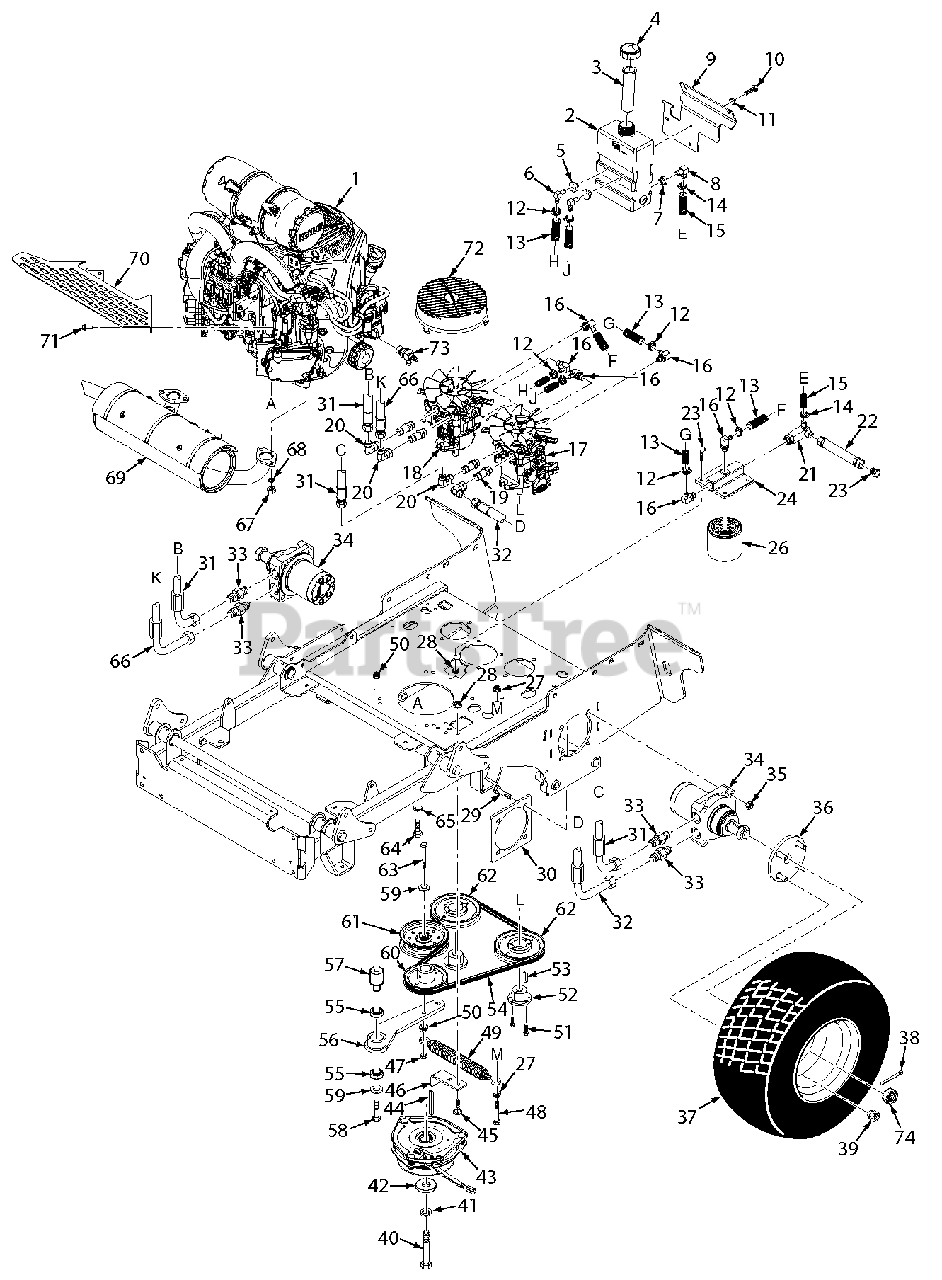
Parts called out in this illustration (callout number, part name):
1	Engine, 22 HP Kawasaki FX
1	Engine, 23 HP Kawasaki FX
1	Engine, 25 HP Kohler EFI
1	Engine, 25 HP Kawasaki FX
1	Engine, 29 HP Kohler EFI
2	Hydro Tank Assy., SVRII
3	Insert, Filler Neck
4	Cap, Hydro Tank
5	Bushing, .56 Viton
6	Fitting, 90 Degree x .38 Hose
7	Bushing, .78 Viton
8	Fitting, 90 Degree x .50 Hose
9	Bracket, Hydro Tank Mounting
10	Bolt, Hex Head 5/16-18 x 3/4"
11	Lockwasher, 5/16"
12	Clamp, Hose
13	Hose, 3/8" Pushlock (order by inch)
14	Clamp, Hose
15	Hose, 1/2" Pushlock (order by inch)
16	Elbow, 90 Degree - O-Ring
17	Pump, LH - SVRII
18	Pump, RH - SVRII
19	Union, O-Ring to JIC
20	Elbow, JIC Swivel
21	Tee, 3/4 O-Ring
22	Drain, Hose Assembly
23	Plug, JIC 3/4-16 UNF
24	Filter Head
25	Bolt, Hex Head 5/16-18 x 3/4"
26	Filter
27	Nut, Serrated Flange 3/8-16
28	Nut, Serrated Flange 5/16-18
29	Bolt, Hex Head 1/2-13 x 2-1/2"
30	Plate, Motor Backing
31	Hose Assy., 27-1/2"
32	Hose Assy., 15-1/4"
33	Tube, Union 1/2 x 5/8
34	Wheel Motor, SVRII
35	Nut, Center Lock 1/2-13
36	Wheel Hub Assy., SVRII
36	Serrated Bolt, 1/2-20 x 1.563
37	Wheel Assy., 24 x 9.5 - 12 (4-Ply) (48 / 52)
37	Tire, 24 x 9.5 - 12 (4-Ply)
37	Rim w/Stem
37	Wheel Assy., 24 x 12 - 12 (4-Ply) (61)
37	Tire, 24 x 12 -12 (4-Ply)
38	Pin, Cotter 9/64 x 1"
39	Wheel Nut
40	Bolt, Hex Head 7/16-20 x 2-1/4" w/ Patch
41	Lockwasher, 3/8"
42	Flatwasher, 7/16-.469 x 1.75 x .25
43	Clutch w/Tag GT2.5-FE02 (48 / 52)
43	Clutch w/Tag GT3.5-FE05 (61)
44	Key, 1/4 x 1/4 x 3-1/2"
45	Bolt, Carriage 5/16-18 x 3/4"
46	Anti-Rotation Bracket
47	Nut, Center Lock 3/8-16
48	Bolt, Hex Head 3/8-16 x 3"
49	Spring, Transmission Idler
50	Nut, Elastic Stop 3/8-16
51	Bolt, Hex Head 1/4-20 x 1"
52	Tapered Hub, 15mm Bore
53	Key, 5 x 5 x 25mm
54	Belt, Transmission
55	Bearing
56	Idler Arm Assy.
57	Pivot, Idler
58	Bolt, Hex Head 3/8-16 x 3-1/4"
59	Flatwasher, 3/8-.391 x .938 x .105 HD
60	Pulley, 4.75" OD - 1.125 Bore
61	Pulley, 4-1/2" Idler
62	Pulley, 5.45" OD - Tapered Bore
63	Bolt, Hex Head 3/8-16 x 2-3/4" Full Thread
64	Bolt, Hex Head 3/8-16 x 1-1/4" (Kawasaki)
64	Bolt, Hex Head Self-Tap 3/8-16 x 1-1/4" (Kohler x3 - 25EFI, Kohler x4 - 29EFI)
64	Bolt, Hex Head 5/16-18 x 1-1/2" (Kohler x1)
64	Lockwasher, 5/16" Ext. Tooth (Kohler x1)
64	Nut, Serrated Flange 5/16-18 (Kohler x1)
65	Lockwasher, 3/8"
66	Hose Assy., 30"
67	Nut, N8-1.25 (Kawasaki)
67	Lock Nut, M8-1.25 -8H (Kohler)
68	Lockwasher, M8 Spring (Kawasaki)
69	Muffler, Kawasaki FX - SVRII
69	Muffler, Kohler CV-EFI - SVRII
69	Muffler, Kawasaki FX801 - SVRII
69	Muffler, Kohler, 29 EFI - SVRII
70	Heatshield, Muffler - Kawasaki FX - SVRII
70	Heatshield, Muffler - Kawasaki FX801 - SVRII
70	Heatshield, Muffler - Kohler 29 EFI - SVRII
71	Bolt, M8-1.25 x 20 Flanged HD
71	Bolt, Hex Head 5/16-18 x 3/4" - 23HP FX
71	Flatwasher, 5/16-.344 x .688 x .065
71	Nut, Serrated Flange 5/16-18
72	Fan Cover, Pump
73	Oil Drain, M20 Thread (Kawasaki)
73	OIl Drain, 3.3" (Kohler 25HP-EFI)
74	Nut, Hex Castle
